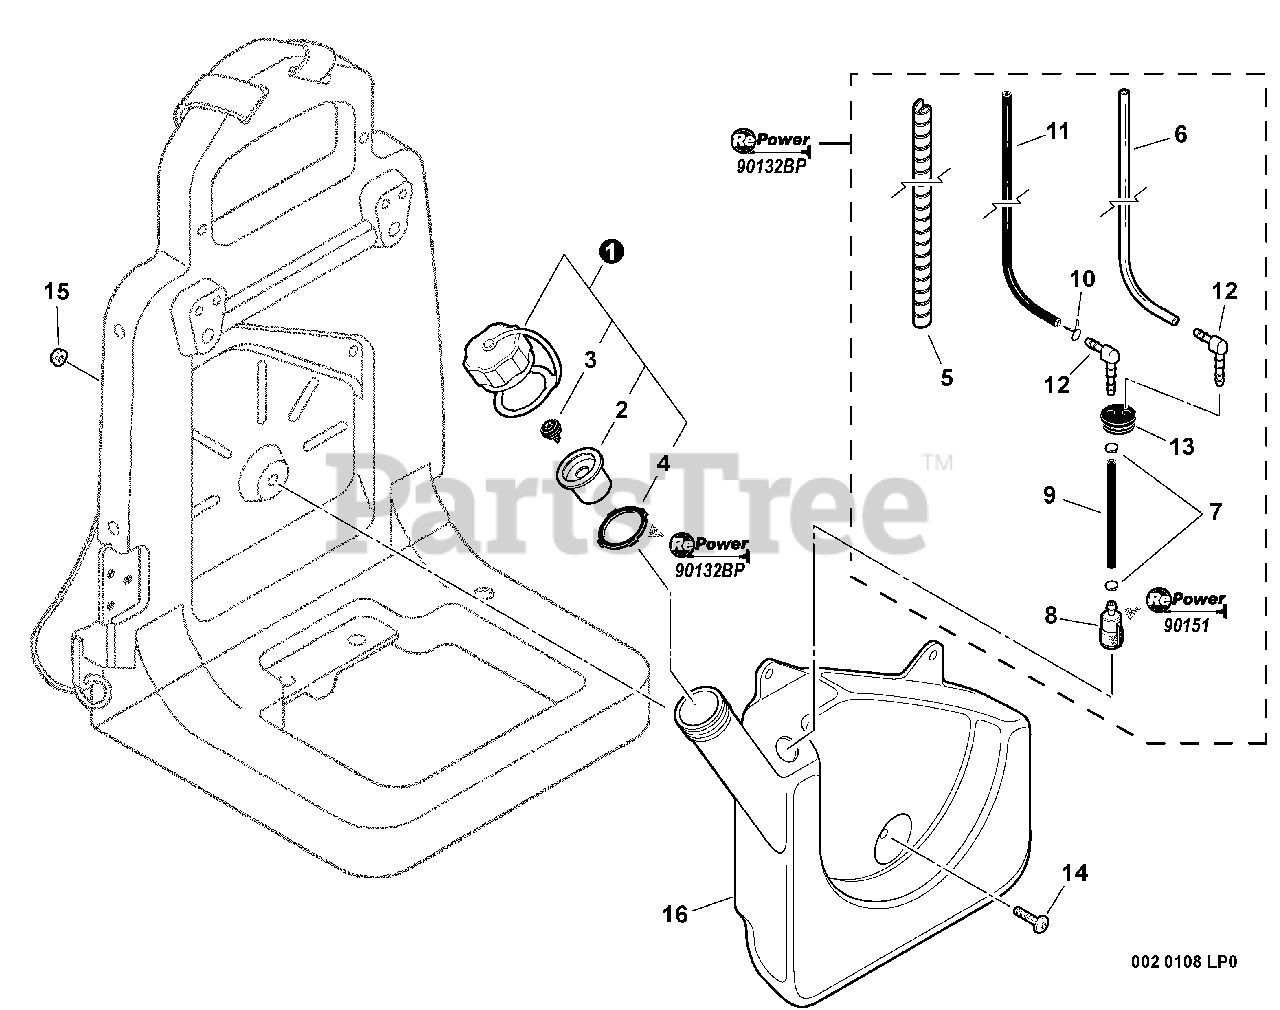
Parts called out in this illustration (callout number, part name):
1	CAP ASSY
2	VENT HOLDER ASSY
4	GASKET, CAP
5	WRAP, SPIRAL
6	PIPE - 3X6X470 -- CLEAR
7	CLIP - 6.5
8	FILTER, FUEL
9	PIPE - 3X6X280 -- BLACK
10	CLIP - BUTTERFLY
11	PIPE - 3X5X470 -- BLACK
12	CONNECTOR, PIPE
13	GROMMET
14	SCREW - 5X20
15	NUT - 5 -- FLANGE
16	TANK, FUEL
17	RePower FUEL SYSTEM KIT
18	RePower TUNE-UP KIT
